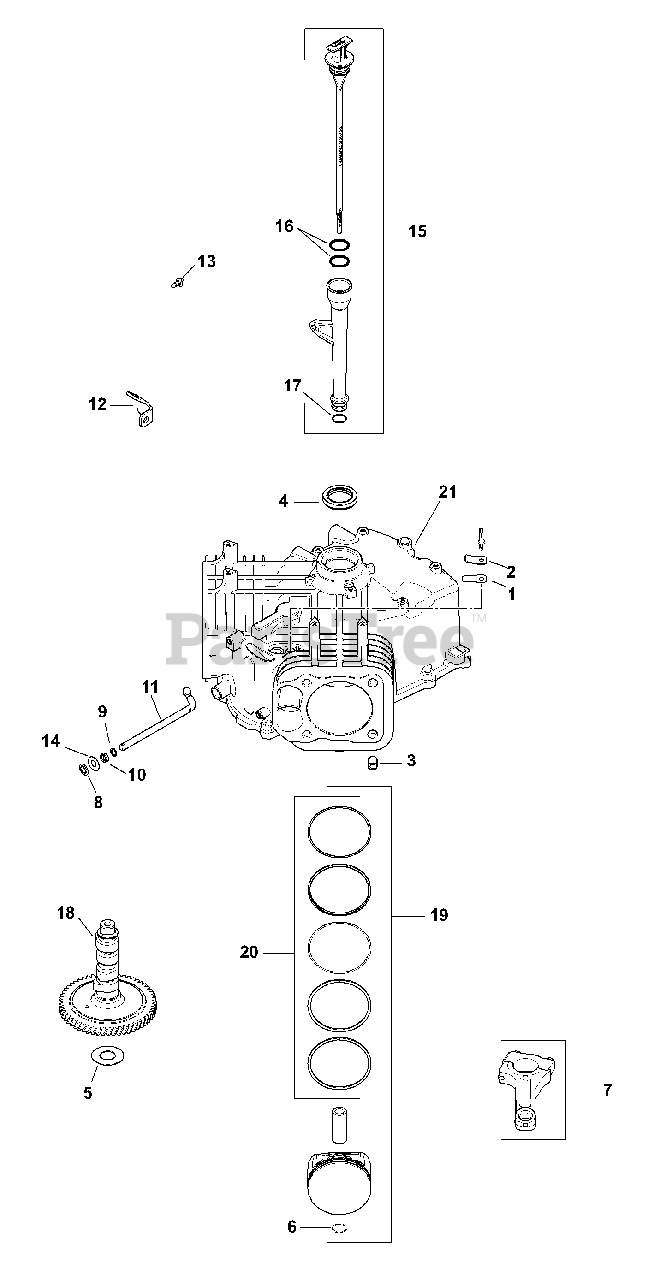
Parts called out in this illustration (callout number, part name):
1	Breather Reed
2	Breather Reed Retainer
4	Oil Seal, 1.78 x 1.26
5	Camshaft Shim, .028 (White)
5	Camshaft Shim, .03 (Blue)
5	Camshaft Shim, .032 (Red)
5	Camshaft Shim, .034 (Yellow)
5	Camshaft Shim, .036 (Green)
5	Camshaft Shim, .038 (Gray)
5	Camshaft Shim, .04 (Black)
6	Piston Pin Retainer
7	Connecting Rod (STD)
8	Ring Retainer
9	Flat Washer, 11/32
10	Governor Cross Shaft Seal
11	Governor Cross Shaft
12	Oil Fill Tube Bracket
13	Flange Screw, M5 x .8 x 13
14	Flat Washer, 9mm
15	Dipstick & Tube Kit
17	Lower Oil Fill Tube O-Ring
18	Camshaft Assembly
19	Piston Kit w/ Ring
19	Piston Kit w/ Ring (0.25) 83mm
19	Piston Kit w/ Ring (0.08) 83mm
20	Ring Set, Piston STD
20	Ring Set, Piston (.08)
20	Ring Set, Piston (.25)
